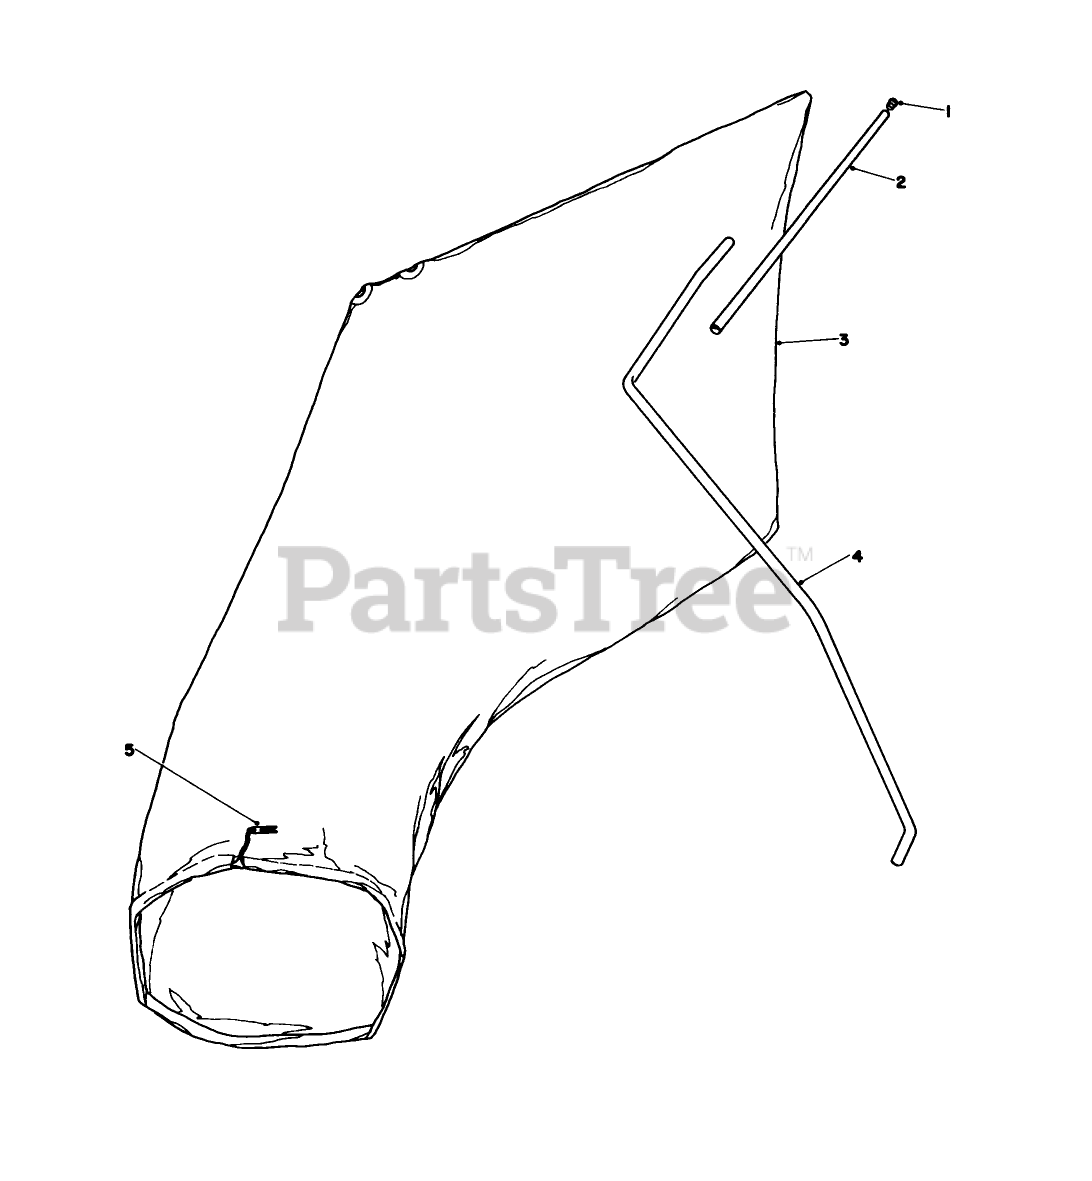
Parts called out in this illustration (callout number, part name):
2	BAG HANGER TUBE
3	Bag (Incl. Ref. #5)
4	HANGER ROD
5	BAG CORD FASTENER
